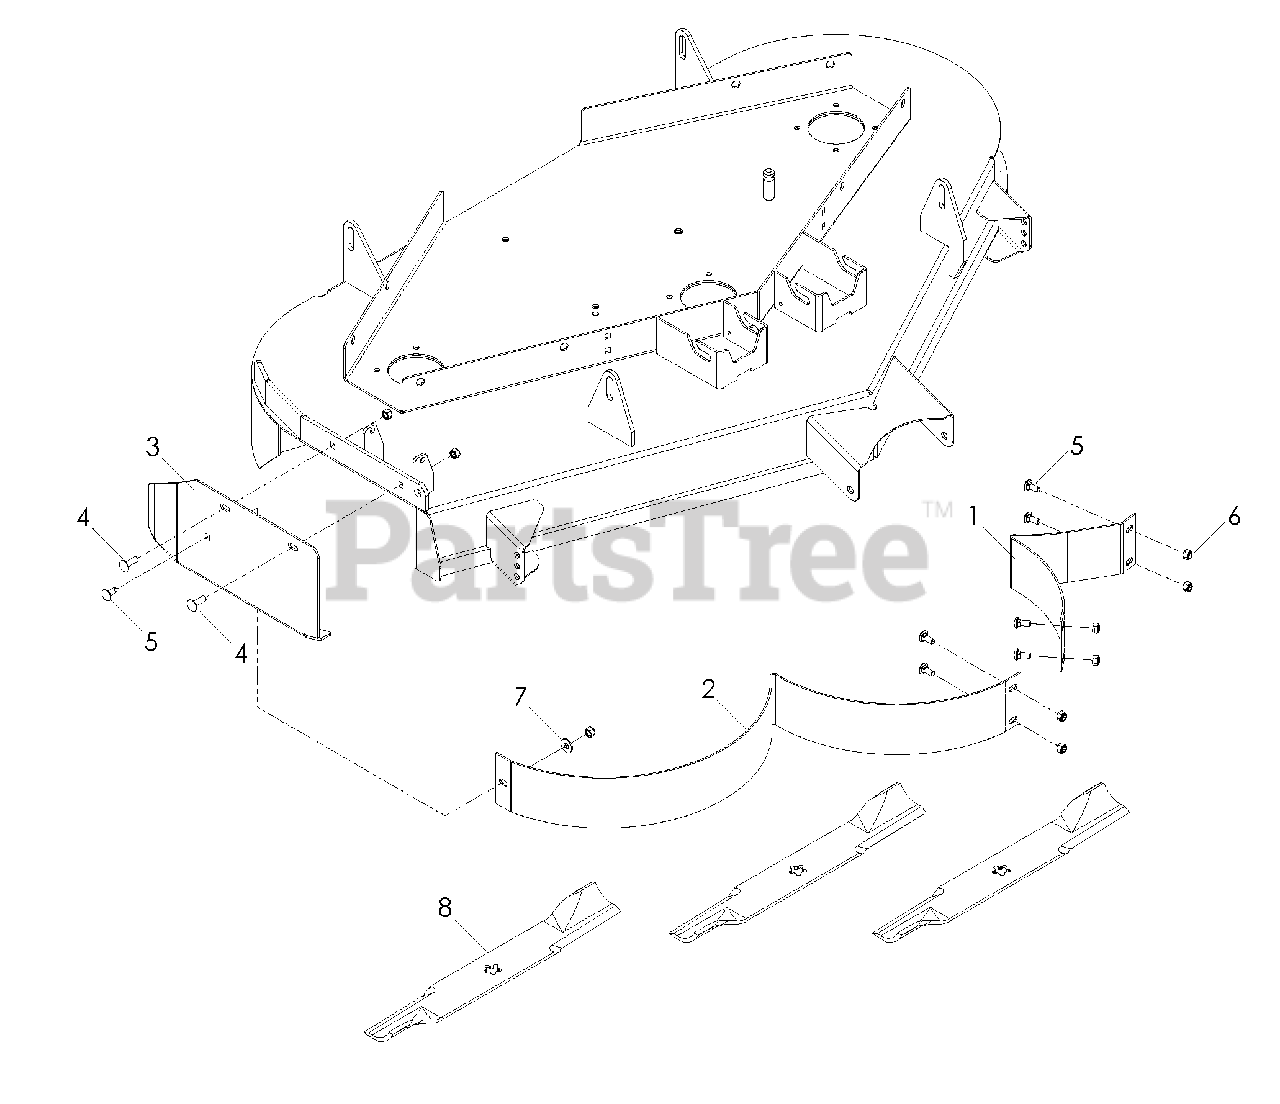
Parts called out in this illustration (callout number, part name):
1	BAFFLE, MULCH, LEFT
2	BAFFLE, MULCH, RIGHT
3	CAP, MULCH, 52
4	RHSNB 5/16 -18 x 1 GR5
5	RHSNB 5/16 -18 X 3/4 GR5
6	NUT 5/16 -18 NYLOC
7	WASHER 5/16
8	BLADE, 18" GATOR
